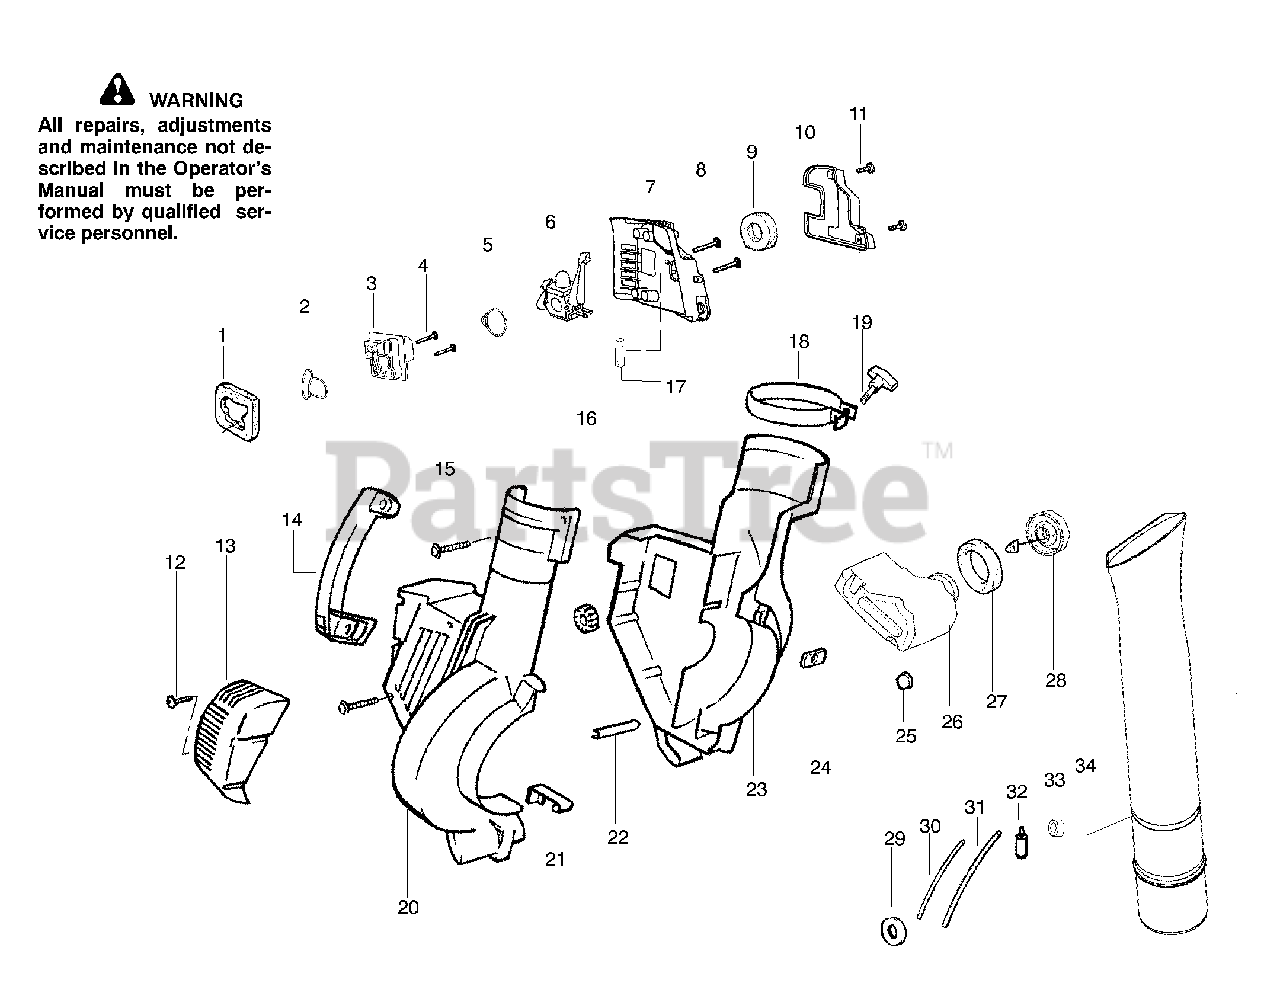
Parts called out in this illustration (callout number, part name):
1	Air Dam (kit)
2	Gasket-Carb. Adapter/Cyl. (kit)
3	Carburetor Adaptor
5	Gasket-Carburetor (kit)
6	Kit-Carb Ass'y. (C1Q-W11)
8	Screw-Carb.
9	Filter-Air
10	Cover-Air Filter
11	Screw-Air Box Cover
13	Assy-Muffler Cover
16	Isolator
17	Foam 25.4mm (kit)
18	Clamp-Blower Tube
19	Knob-Tube Clamp
20	Housing-Right
21	Spring-Cover Latch
22	Guide-Starter Rope
23	Housing-Left
25	Isolator-Crankcase
26	Assy-Fuel Tank
27	Gasket-Fuel Tank
28	Fuel Cap w/Retainer
29	Grommet-Shroud
30	Kit-Line Carb/Purge
31	Kit-Line Tank/Purge
32	Assy-Fuel Pick-up
33	Grommet-Fuel line (kit)
34	Tube-Blower
